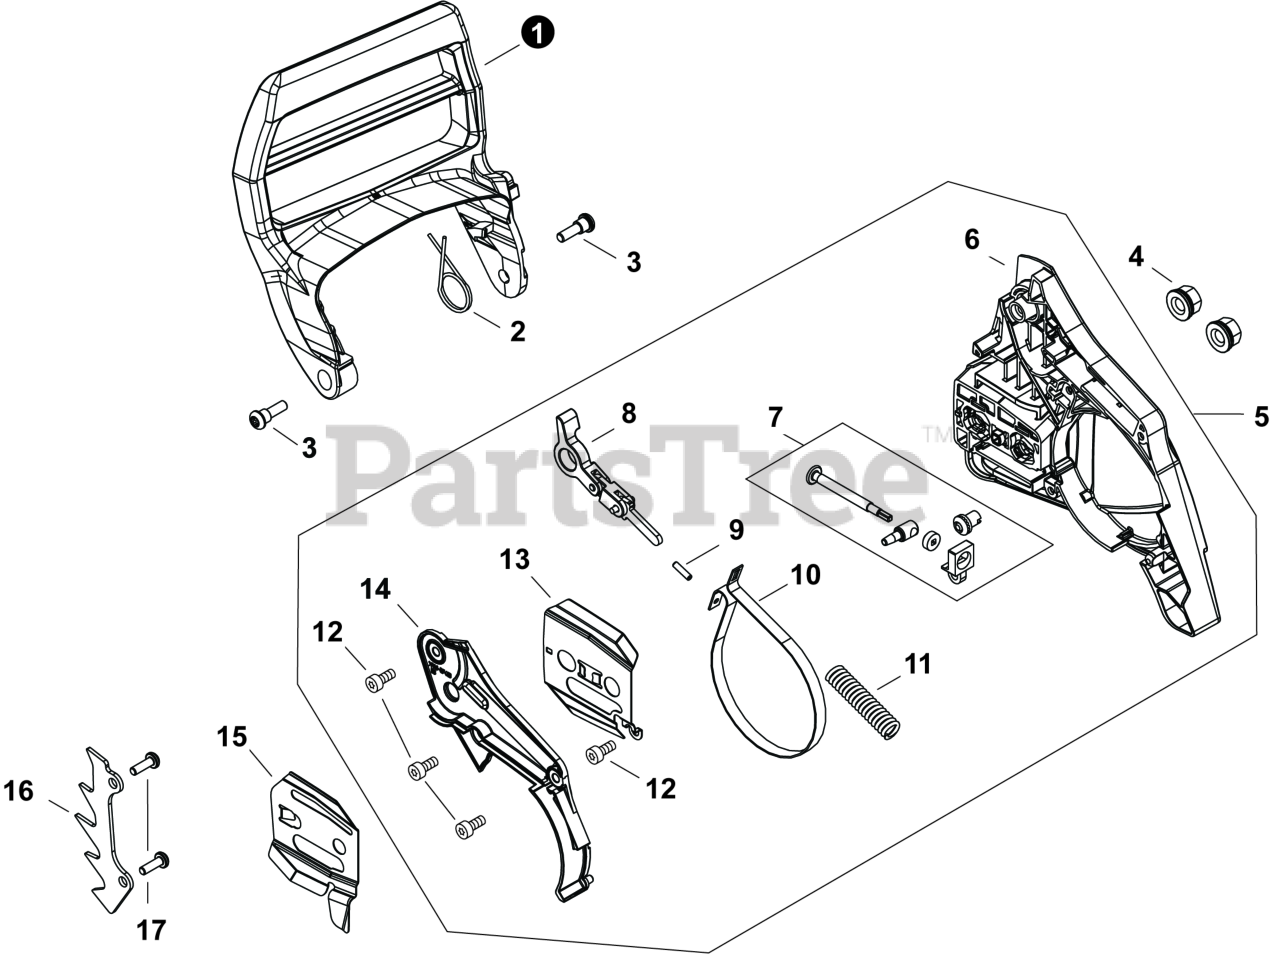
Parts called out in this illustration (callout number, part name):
1	LEVER, BRAKE
2	SPRING, TORSION
3	BOLT, TORX 5x13
4	NUT, FLANGE M8x1.25
5	SPROCKET GUARD ASSY
6	GUARD, SPROCKET
7	TENSIONER KIT, CHAIN
8	CONNECTOR, BRAKE
9	PIN 3x12
10	BAND, BRAKE
11	SPRING, COMPRESSION
12	BOLT, TORX 4x12
13	PLATE, GUIDE - OUTER
14	COVER, BRAKE
15	PLATE, GUIDE - INNER
16	SPIKE, BUMPER
17	BOLT, TORX 5x16
